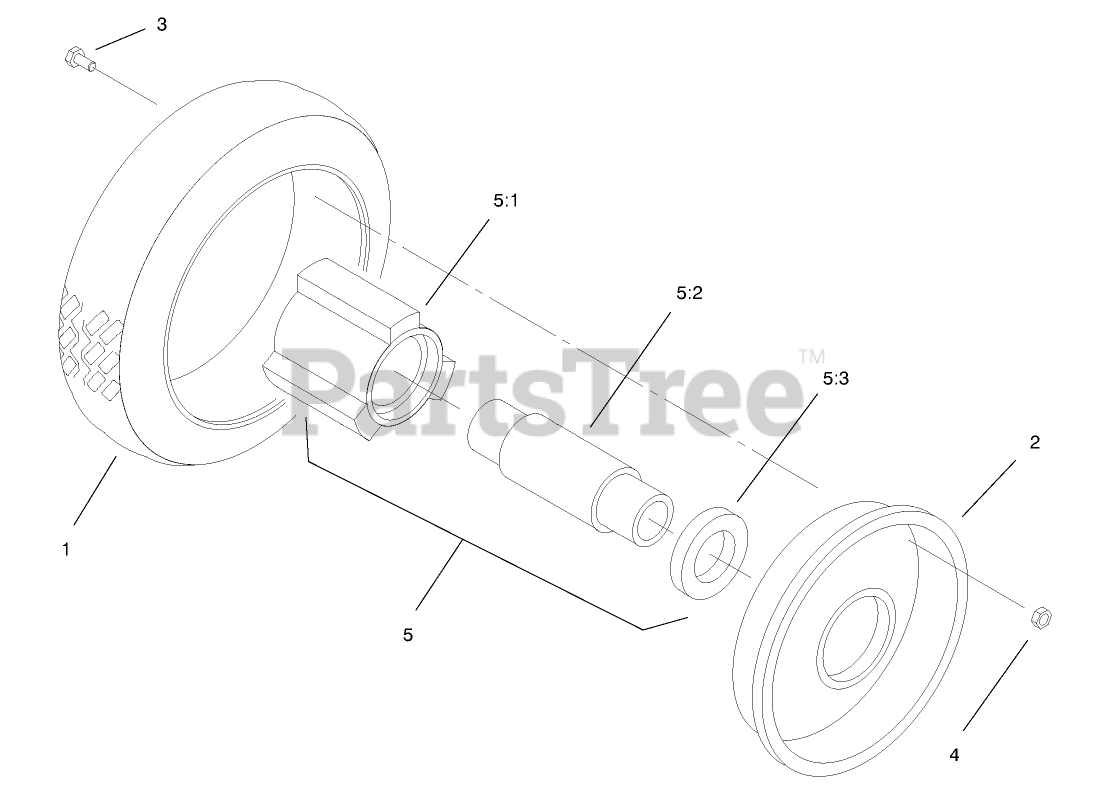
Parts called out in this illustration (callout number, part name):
3	SCREW-HH
4	NUT-LOCK, NI
5	Loose Parts Package
5:1	HUB-BEARING
5:2	SPACER-BEARING
5:3	BEARING-WHEEL
